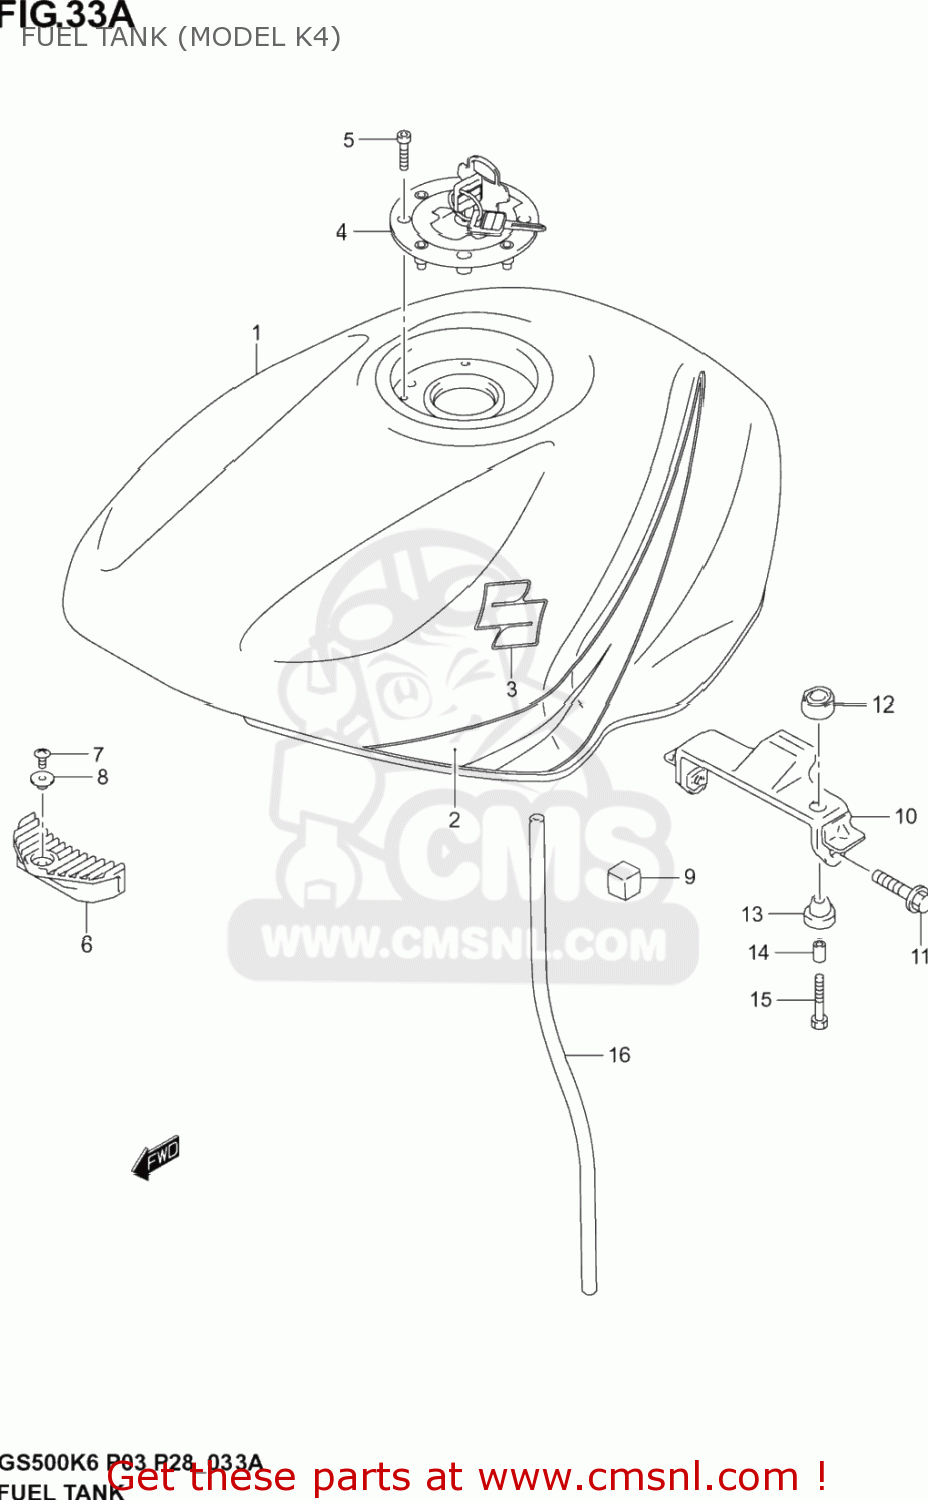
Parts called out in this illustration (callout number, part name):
1	TANK ASSY,FUEL(BLUE)
2	TAPE SET,FUEL TANK
3	EMBLEM,FUEL TA
4	CAP SET,FUEL TANK
5	BOLT(5X20)
6	CUSHION,FUEL TANK FR
7	SCREW
8	WASHER
9	CUSHION,FUEL TANK SIDE
10	BRACKET, REAR
11	BOLT
12	CUSHION
13	CUSHION
14	SPACER(6.5X9X18)
15	BOLT(6X30)
16	HOSE, DRAIN
